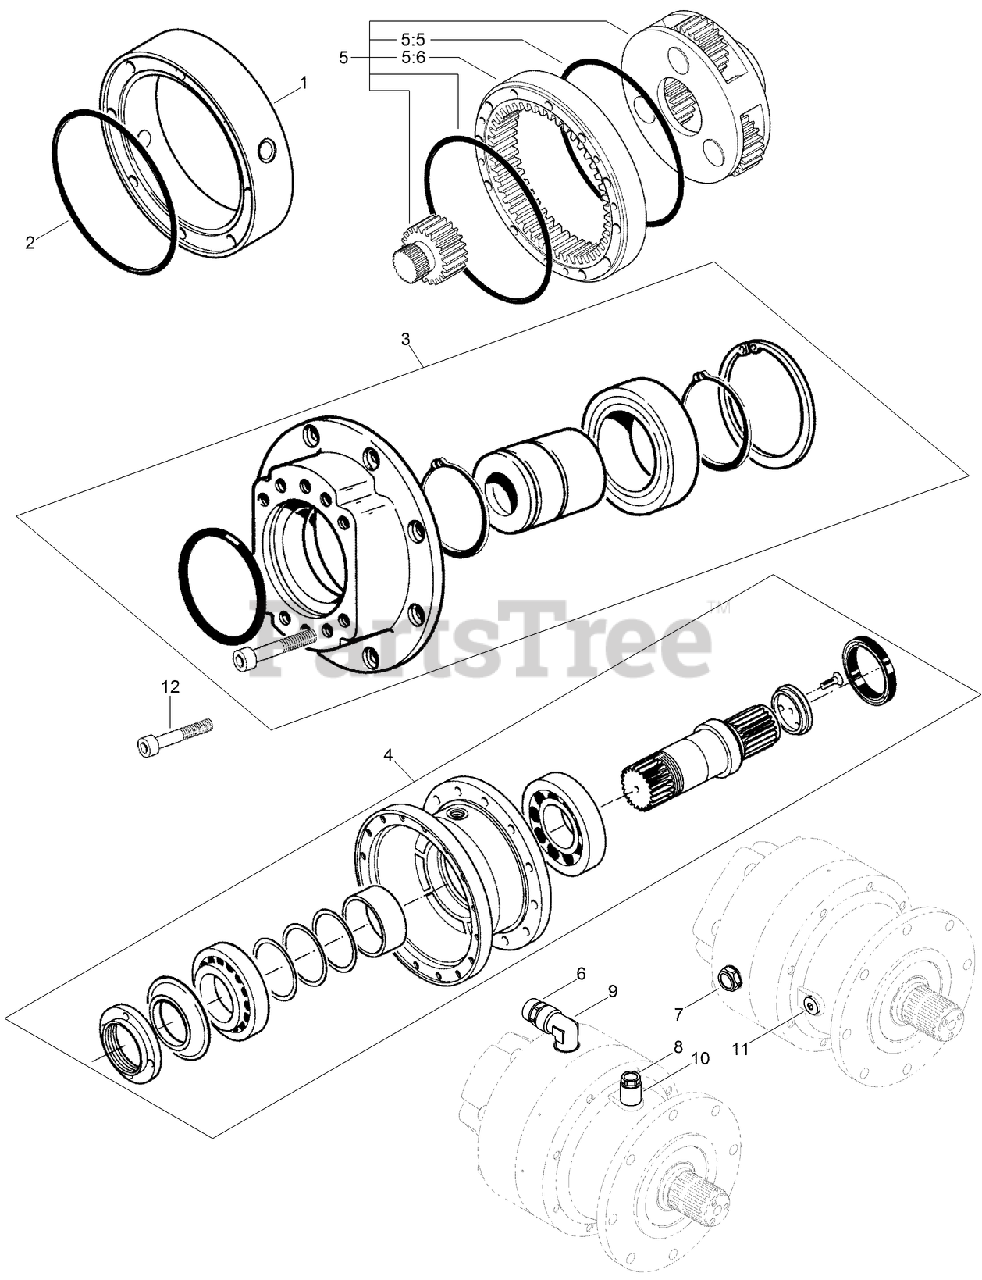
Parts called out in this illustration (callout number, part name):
1	SPACER-RING
2	O-RING
3	HYDRAULIC MOTOR ADAPTER KIT
4	SHAFT-SPLINED, OUTPUT
5	REDUCTION STAGE KIT
5:5	O-RING
5:6	RING-TOOTHED
6	VALVE-BREATHER
7	PLUG-LEVEL
8	PLUG-MAGNETIC
9	ELBOW-90 DEG
10	EXTENSION PIPE WITH WASHER KIT
11	PLUG AND WASHER KIT
